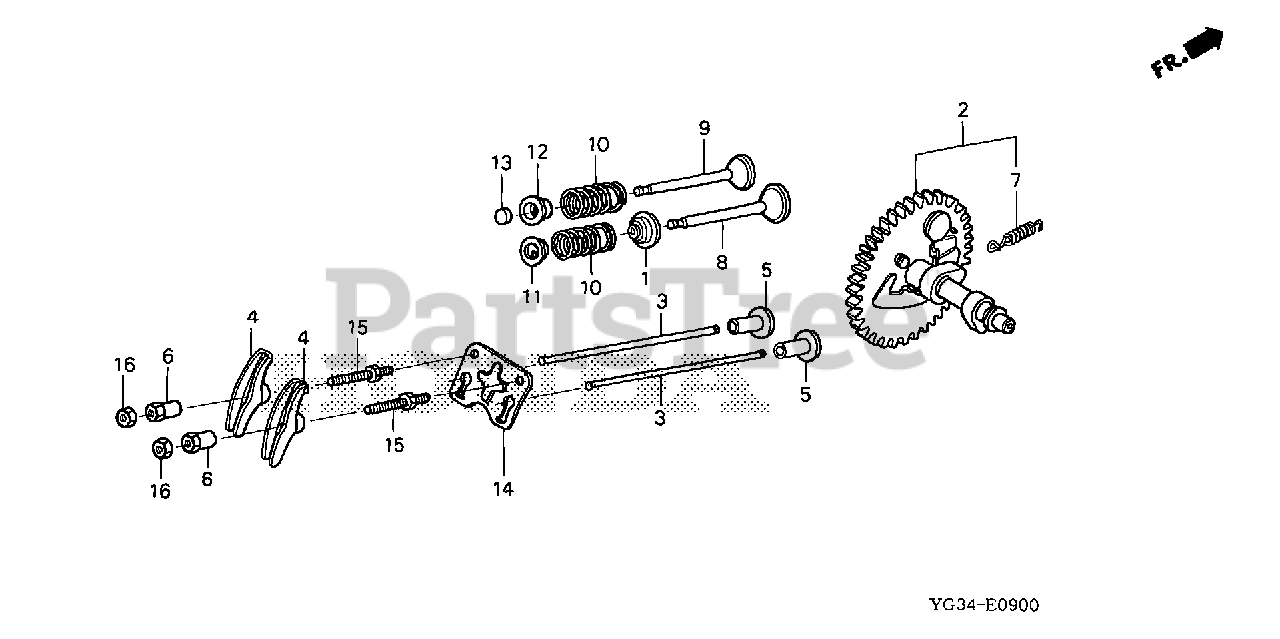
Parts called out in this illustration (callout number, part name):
1	SEAL, VALVE STEM
2	CAMSHAFT ASSY.
4	ARM, VALVE ROCKER
5	LIFTER, VALVE
6	PIVOT, ROCKER ARM
7	SPRING, WEIGHT RETURN
8	VALVE, IN.
9	VALVE, EX.
10	SPRING, VALVE
11	RETAINER, IN. VALVE SPRING
11	RETAINER, VALVE SPRING
12	RETAINER, IN. VALVE SPRING (EXHAUST SIDE)
12	RETAINER, VALVE SPRING (EXHAUST SIDE)
14	PLATE, PUSH ROD GUIDE
15	BOLT, PIVOT (8MM)
16	NUT, PIVOT ADJUSTING
